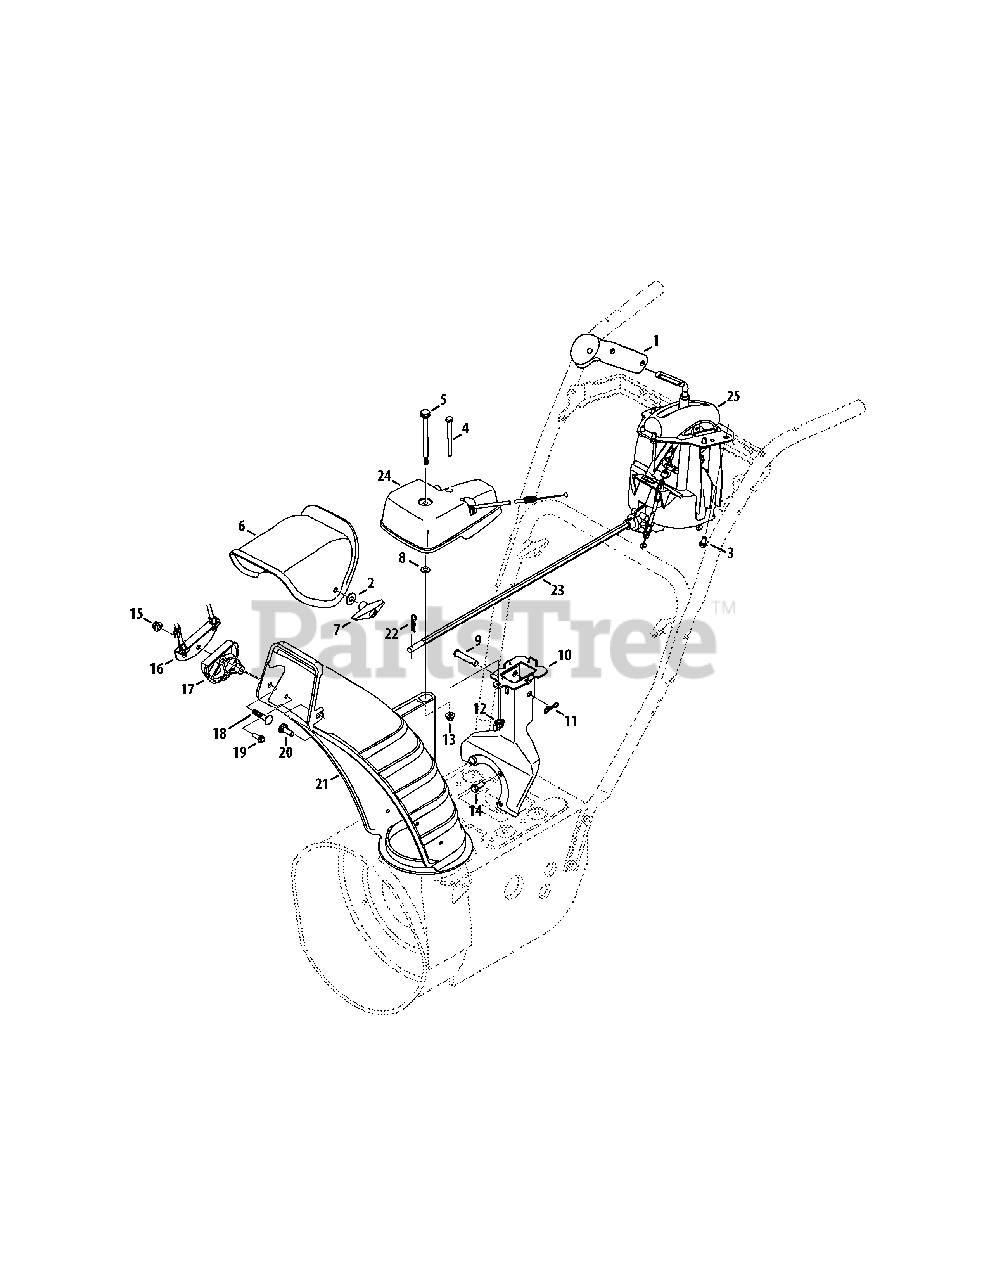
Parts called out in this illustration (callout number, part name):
1	Tigger Housing Assembly Kit
2	Washer, Flat, .349 x .879
3	Hex Washer Screw, 1/4-15 x .50
4	Hex Head Screw, 1/4-20 x 3.00
5	Screw, Shoulder, .312 x 3.5 x 1/4-20
6	Upper Chute
7	Wing Knob, 5/16-18
8	Washer, Flat, .25 x .630
9	Clevis Pin, 3/8 x 1.87
10	Chute Support Bracket
11	Bow-Tie Cotter Pin
12	Wing Nut, 1/4-20
13	Flange Lock Nut, 1/4-20
14	Hex Lock Screw, 5/16-24 x .750
15	Flange Lock Nut, 5/16-18
17	Chute Tilt Cable Guide
18	Carriage Bolt, 5/16-18 x 1.50
19	Hex Washer Screw, 1/4-15 x .750
20	Carriage Bolt, 5/16-18 x 1.00
21	Lower Chute, 5.0
22	Internal Cotter Pin
23	Chute Rod, 3/8 Hex
24	Gearbox Assembly, Chute Rotation
25	4-Way Chute Control Assembly
